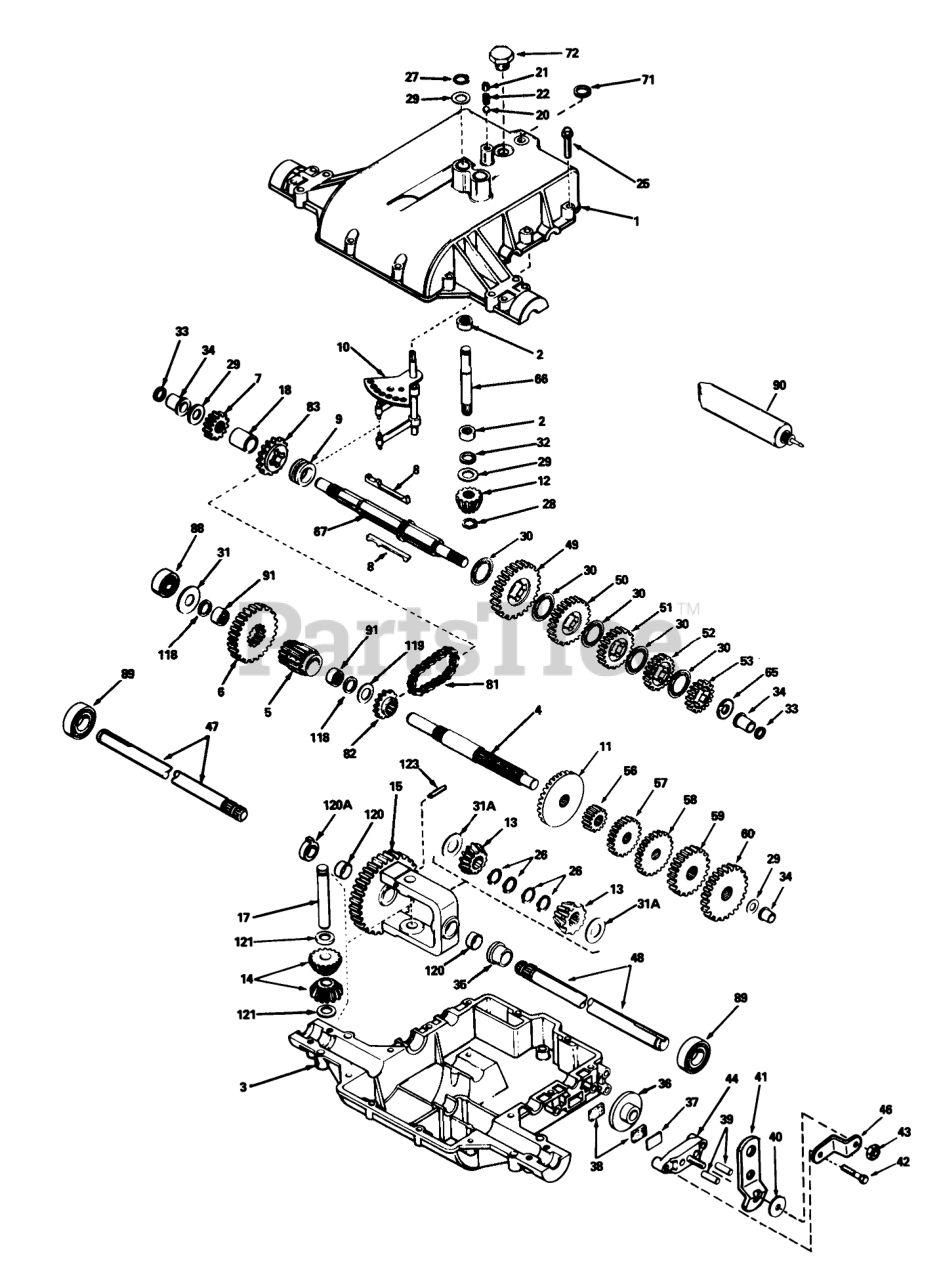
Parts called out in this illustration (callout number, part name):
1	Cover, Transaxle
2	Bearing, Needle
3	Case-transaxle
4	Shaft, Counter
5	Pinion-Output
6	Gear-Output
7	Gear-Spur 15 Teeth
9	Collar-Shift
10	Rod & Fork Assembly
11	Gear-Bevel, 42 teeth
12	Bevel Pinion-Input
13	Gear Bevel
14	Gear Pinion
15	Gear Assy., Differential (Incl. 2 of No. 120)
17	Drive Pin
18	Spacer
20	Ball-Steel
21	Screw-Set
22	Spring
25	Ring Set (.020 O S)
26	Retaining Ring (pkg of 2)
27	Ring-Snap
28	Ring-Retainer
29	Washer
30	Washer
31	Washer-Flat
31A	Washer
32	Seal, Square cut
33	Ring-Square Cut
34	Bushing-Flange
35	Bushing-Flanged
37	Brake Pad Plate
38	Brake Pad
39	Dowel Pin
40	Washer
41	Lever-Brake
42	Ring Set (.020 O S)
43	Locknut
44	Nozzle-Carburetor
46	Bracket
47	Axle (13-1 /4" Long) (Incl. No. 26)
48	Axle (15-1 /8" Long) (Incl. No. 26)
49	Gear-Spur, 37 Teeth
50	Gear-Spur, 30 Teeth
51	Gear-Spur, 25 Teeth
52	Gear-Spur (22 teeth)
53	Gear-Spur 20 teeth
56	Gear-Spur, 12 Teeth
57	Gear-Spur, 20 Teeth
58	Gear-Spur, 25 Teeth
59	Gear-Spur (28 teeth)
60	Gear-Spur (30 teeth)
65	Washer
66	Shaft-Input
67	Shaft, Brake
71	Cut Seal-Square
81	Chain-Roller
82	Sprocket 10t
83	Sprocket (14 Teeth)
88	Bearing, Ball
89	Bearing-Ball
90	Grease 32 Oz
91	Bearing-Needle
118	Ring-Square Cut
119	Washer-Flat
120	Bushing
120A	Bushing
121	Thrust Washer
123	Pin-Roll
